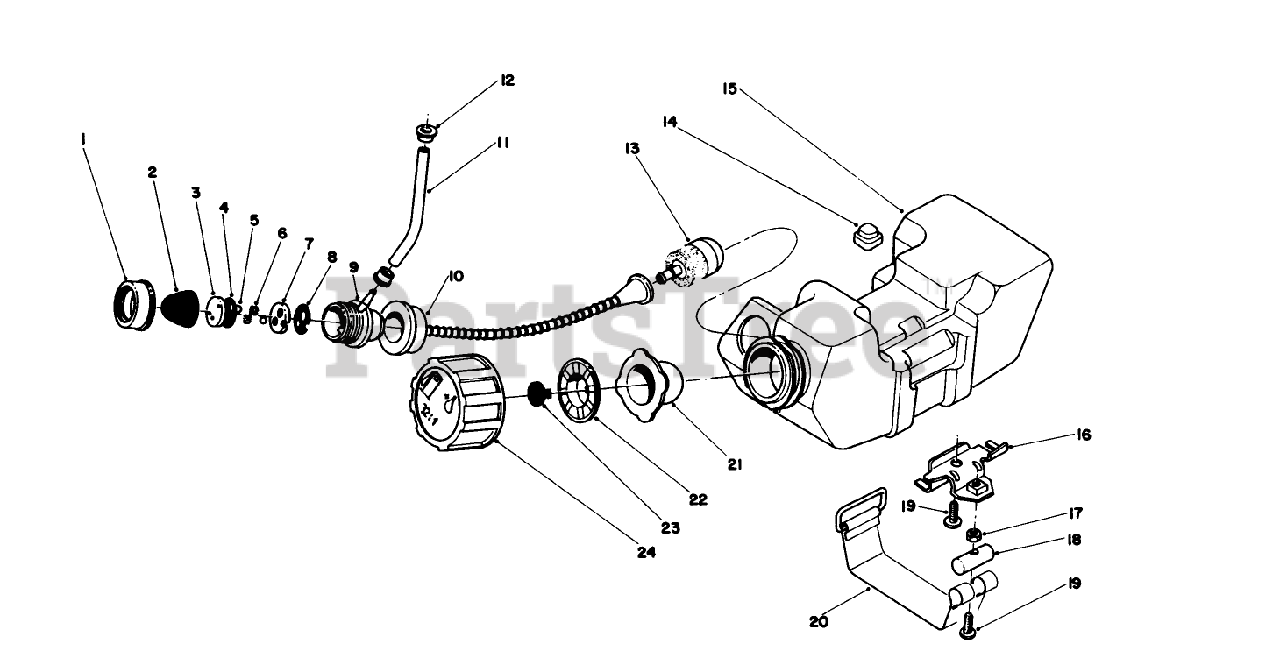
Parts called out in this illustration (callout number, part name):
8	GASKET
9	PRIMER PUMP
10	HOSE, SUCTION
20	BAND, TANK
21	GASKET - PACKING
22	HOLDER
23	BREATHER VALVE
24	TANK CAP ASM
